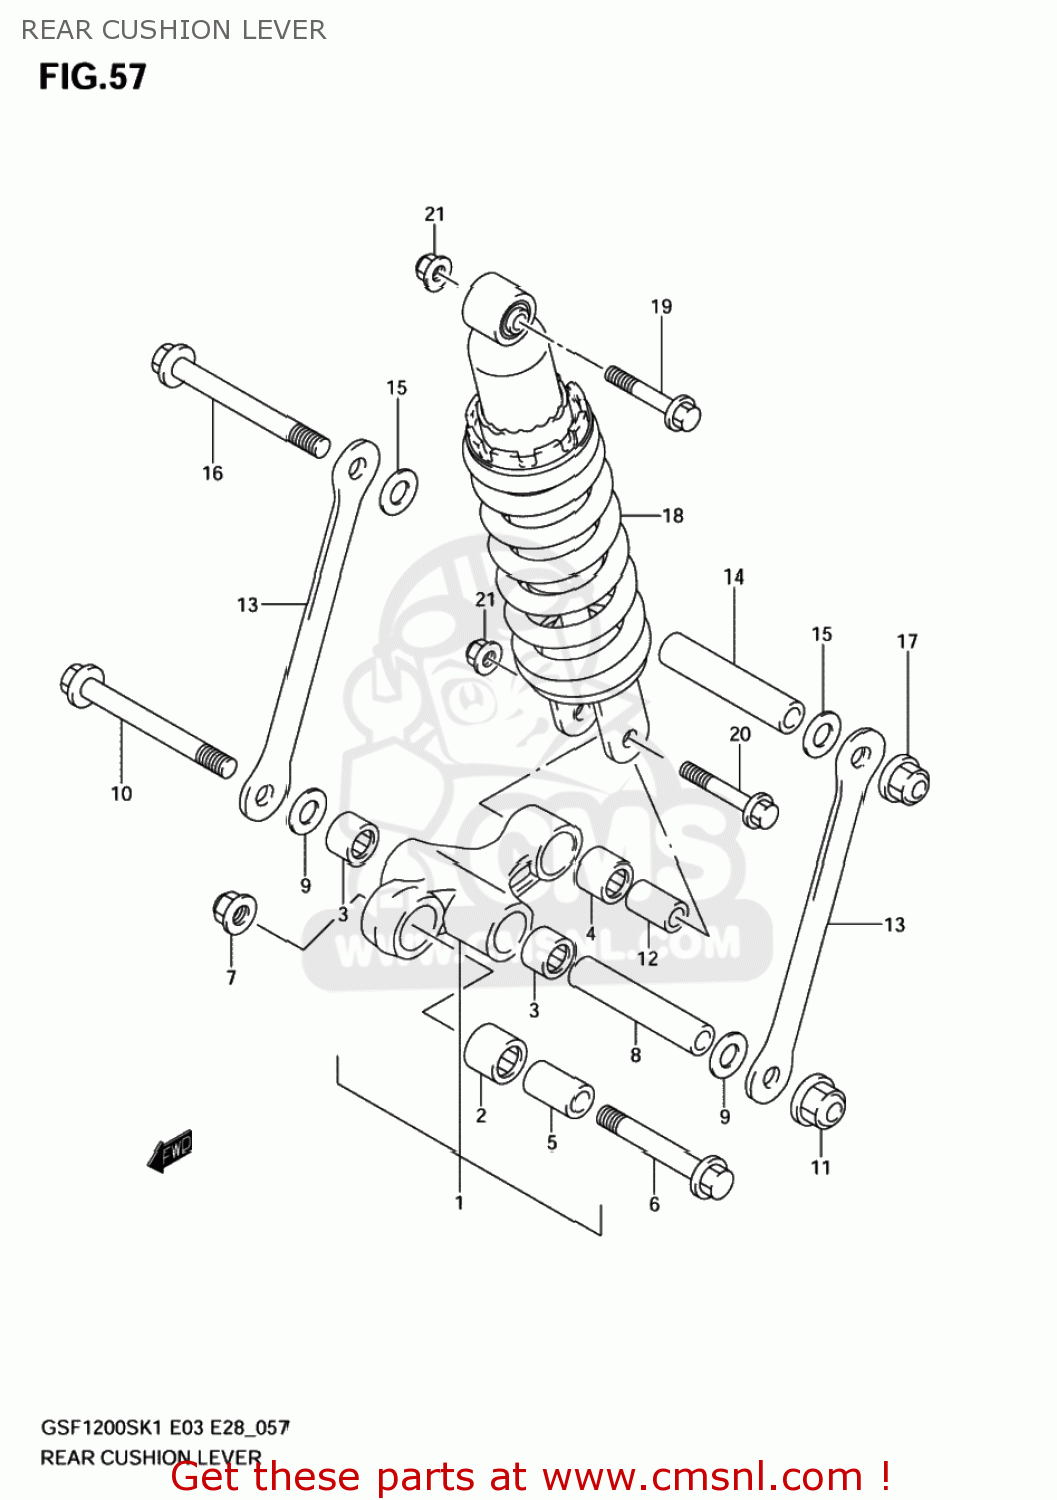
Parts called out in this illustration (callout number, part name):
1	LEVER SET,RR CUSHION
2	BEARING(20X27X26)
3	BEARING(17X24X25)
4	BEARING(17X24X26)
5	SPACER,RR CUSHION LEVER FR
6	BOLT,CUSHION LEVER FR
7	NUT 12MM
8	SPACER(12X17X89)
9	WASHER(12X34X1)
10	BOLT,REAR CUSHION ROD
11	NUT 12MM
12	SPACER,RR CUSHION LEVER
13	ROD,RR CUSHION
14	SPACER(12X17X89)
15	WASHER(12X34X1)
16	BOLT,REAR CUSHION ROD
17	NUT 12MM
18	ABSORBER ASSY,RR SHOCK
19	BOLT,RR CUSHION ROD UPR
20	BOLT,RR SHOCK ABSORBER
21	NUT
